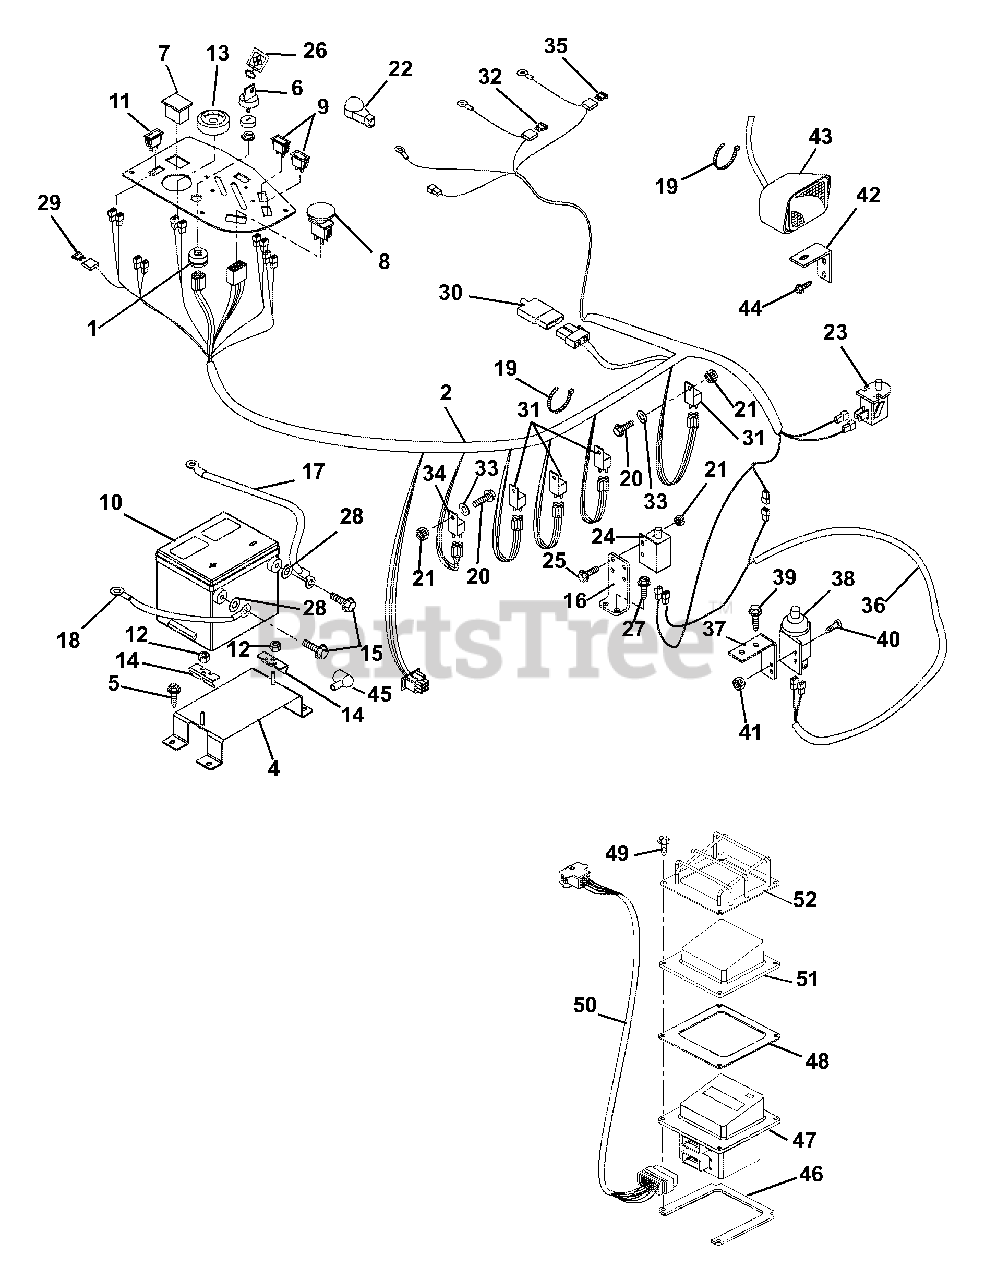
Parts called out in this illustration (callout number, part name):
1	Switch, Ignition (Diesel) (060, 061, 075, 076, 318, 319)
1	Switch, Ignition (058, 059, 073, 074)
2	Harness, Wiring (Diesel) (060, 061, 075, 076, 318, 319)
3	Harness, Wire (Gas) (058, 059, 073, 074)
4	Weldment, Battery Support
5	Screw-Tapping .38-16 x .75 Hex Washer Head
6	Key-with Cap
6	Ignition Key Set
7	Plug (0273, 074, 075, 076, 318, 319)
7	Hour Meter (058, 059, 060, 061)
8	Switch-Clutch With Retainer Ring
9	Light-Indicator Kit (060, 061, 075, 076, 318, 319)
9	Light-Indicator Kit (058, 059, 073, 074)
10	Battery with Tube
11	Switch, Light
12	Nut-Locking-Top-Flange .31-18
13	Gauge, Temperature
14	Bracket, Battery Hold-Down
15	Bolt-Hex .25-20 x .75 Grade 5
16	Mount, Safety Switch
17	Positive Cable (060, 061, 075, 076, 318, 319)
17	Positive Cable (058, 059, 073, 074)
18	Cable, Negative Battery (060, 061, 075, 076, 318, 319)
18	Ground Cable (058, 059, 073, 074)
19	Cable Tie
20	Screw-Machine 10-24 x .75 Hex Washer Head (060, 061, 075, 076, 318, 319)
20	Screw-Machine 10-24 x .75 Hex Washer Head (058, 059, 073, 074)
21	Nut-Locking-Nylon 10-24 With Insert (060, 061, 075, 076, 318, 319)
21	Nut-Locking-Nylon 10-24 With Insert (058, 059, 073, 074)
22	Eyelet Terminal Boot
23	Switch, Snap Mounting (N.O.)
24	Switch-Single Pole
25	Screw-Machine 10-24 x .75 Hex Washer Head
26	Key Chain
27	Screw-Tapping .25-20 x .50 Hex Washer Head
28	Washer-Flat-Steel .406 x 1.00 x .083
29	Fuse, 15 Amp
30	Diode, Connector Shell
31	Relay
32	Fuse, 30 Amp
33	Washer-Flat-Steel .25 x .562 x .049 (060, 061, 075, 076, 318, 319)
35	Fuse, 50 AMP (Maxi Fuse)
35	Fuse, 25 Amp
36	Harness, Wire Adapter CE (318, 319)
37	Mount- Switch (318, 319)
38	Switch-Single Pole (N.O.) with Cover (318, 319)
39	Screw-Tapping .31-18 x .50 Hex Washer Head (318, 319)
40	Screw-Machine 10-24 x .75 Hex Washer Head (318, 319)
41	Nut-Locking-Nylon 10-24 with Insert (318, 319)
42	Bracket, Headlight Mounting
43	Headlight
44	Screw-Tapping .38-16 x .50 Hex Washer Head
45	Boot, Eyelet Terminal
46	Spacer, Enclosure Mounting (Bottom) (073, 074, 075, 076, 318, 319)
47	Assembly, Eye-Q (073, 074, 075, 076, 318, 319)
48	Gasket, Eye-Q (073, 074, 075, 076, 318, 319)
49	Screw, Machine 10-24 x 1.0 Slotted Pan Black (073, 074, 075, 076, 318, 319)
50	Harness Jumper (Eye-Q) (073, 074, 075, 076, 318, 319)
51	Guard, Element (073, 074, 075, 076, 318, 319)
52	Guard, Vinyl Eye-Q (073, 074, 075, 076, 318, 319)
